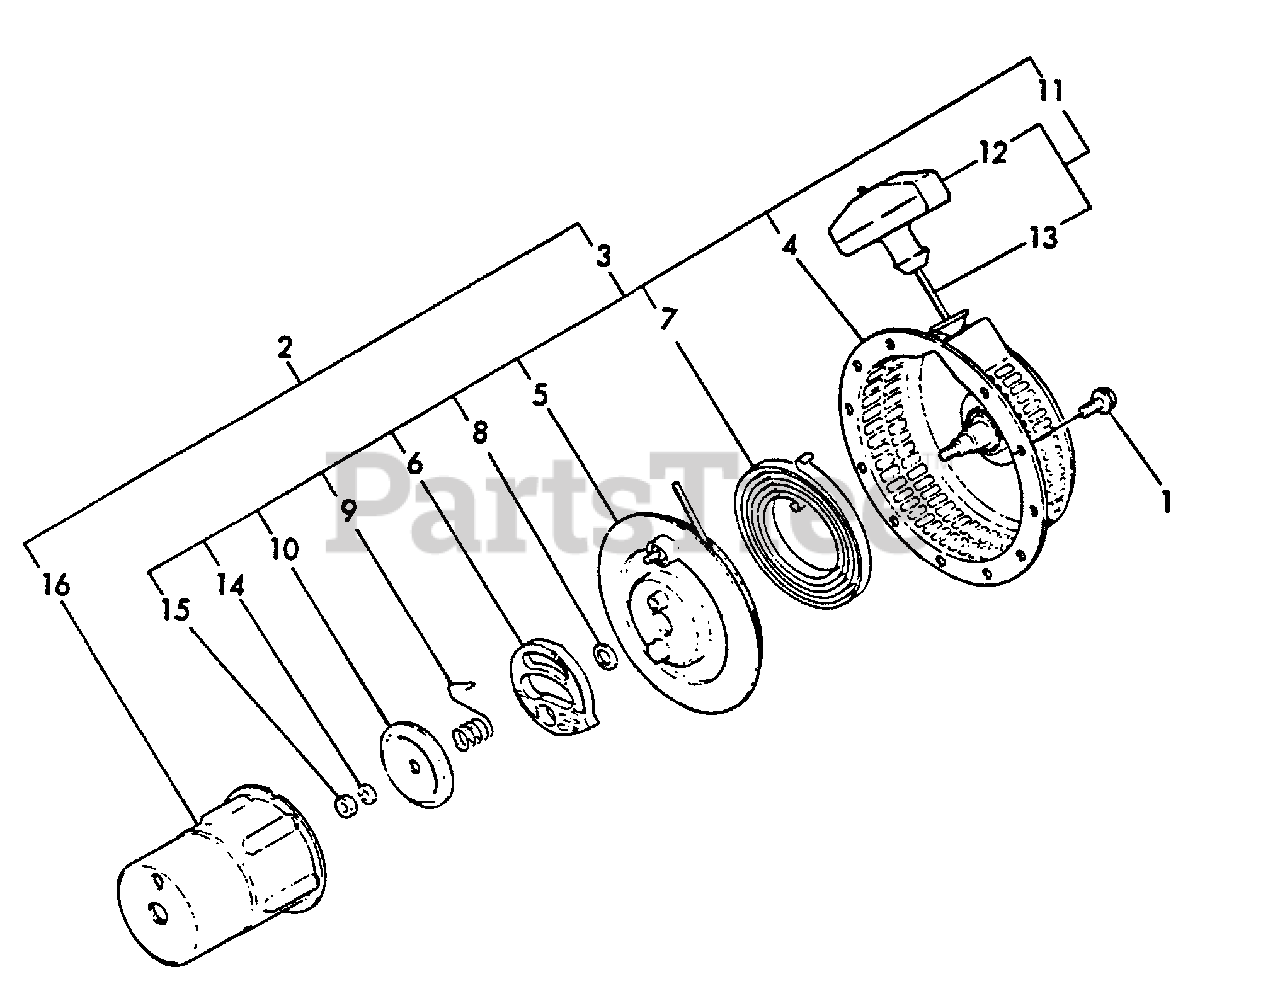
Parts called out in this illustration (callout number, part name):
1	BOLT - 6×8 -- PLATED
2	STARTER ASSY
3	STARTER ASSY, RECOIL
4	CASE, STARTER
5	REEL
7	SPRING, SPIRAL
8	WASHER
9	SPRING, FRICTION
10	PLATE, FRICTION
11	STARTER ROPE ASSY
12	GRIP, STARTER
13	ROPE, STARTER
14	LOCKWASHER - 6
15	NUT - 6
16	PULLEY, STARTER
